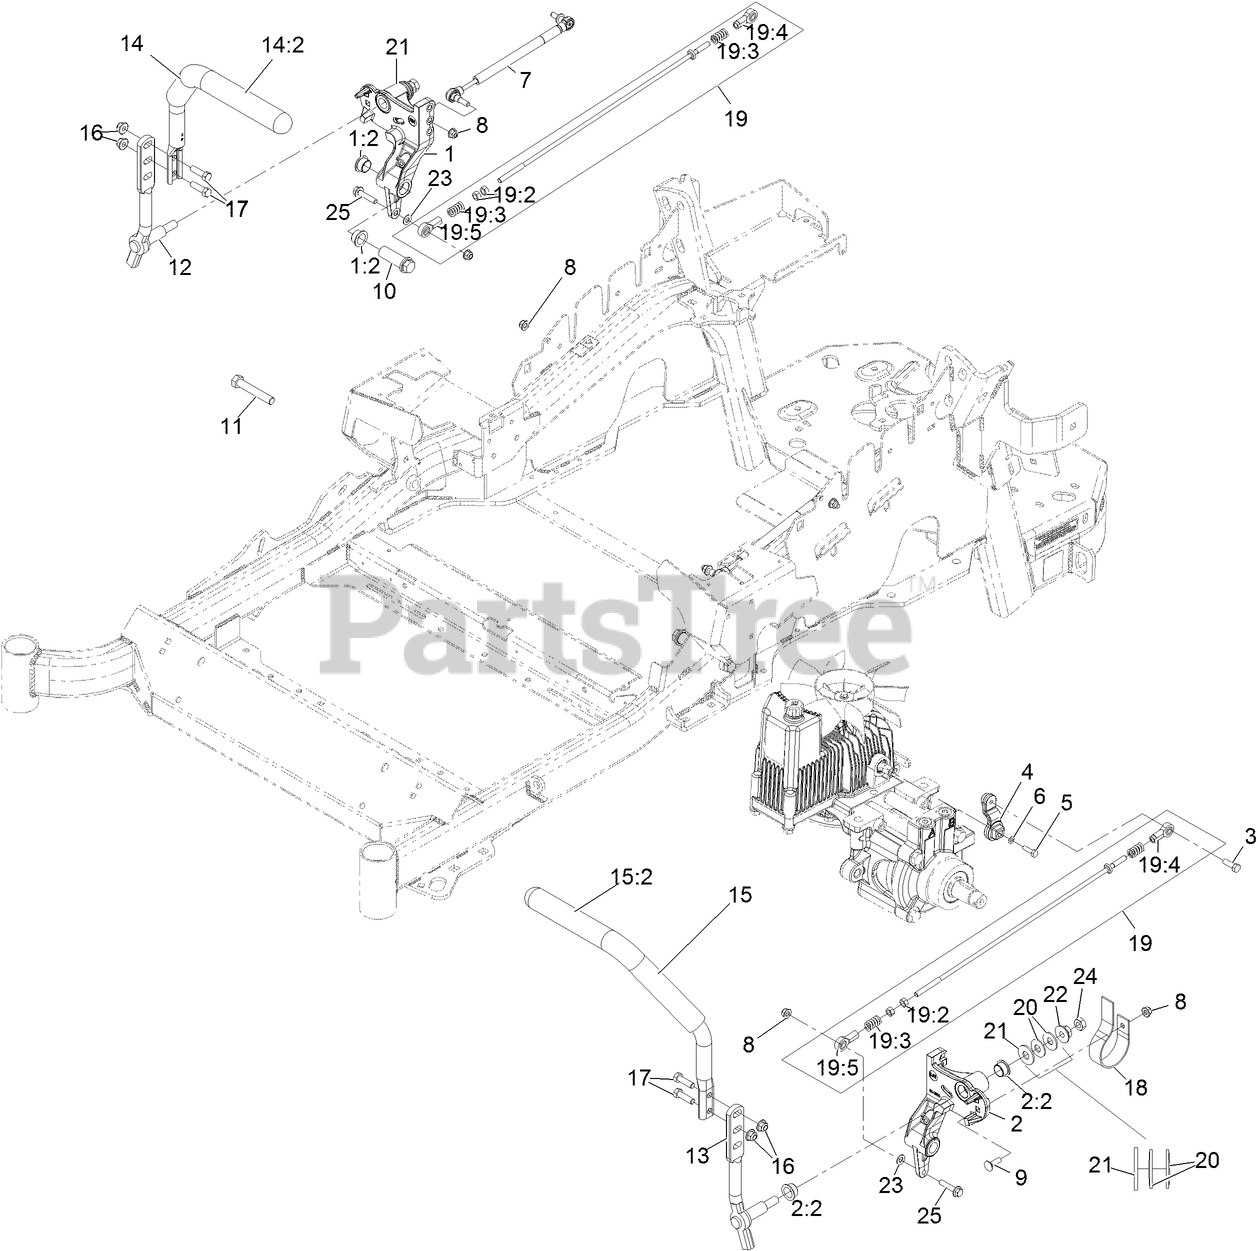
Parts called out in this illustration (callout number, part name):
1	RH MOTION CONTROL AND BUSHING ASM
1:2	BUSHING-FLANGE
2	LH MOTION CONTROL AND BUSHING ASM
2:2	BUSHING-FLANGE
3	SCREW-HH, THREAD LOCKING
4	ARM-CONTROL, PUMP
5	SCREW-HH
6	WASHER-SPRING
7	DAMPER-CONTROL, MOTION
8	NUT-HF, NI
9	BOLT-CARR
10	HUB-THREADED
11	SCREW-HH
12	LEVER-CONTROL MOTION, RH
13	LEVER-CONTROL MOTION, LH
14	ASM-HANDLE-RH
14:2	GRIP-CONTROL, LEVER
15	LH HANDLE ASM
15:2	GRIP-CONTROL, LEVER
16	NUT-HF, NI
17	SCREW-HH
18	SPRING-LEAF
19	PUMP LINKAGE REAR ASM
19:2	NUT-HEX
19:3	SPRING-COMPRESSION
19:4	BALLJOINT-LH
19:5	BALLJOINT-RH
20	WASHER-SPRING
21	WASHER-FLAT
22	NUT-HF
23	WASHER-PLAIN
24	NUT-JAM
25	SCREW-HHF
